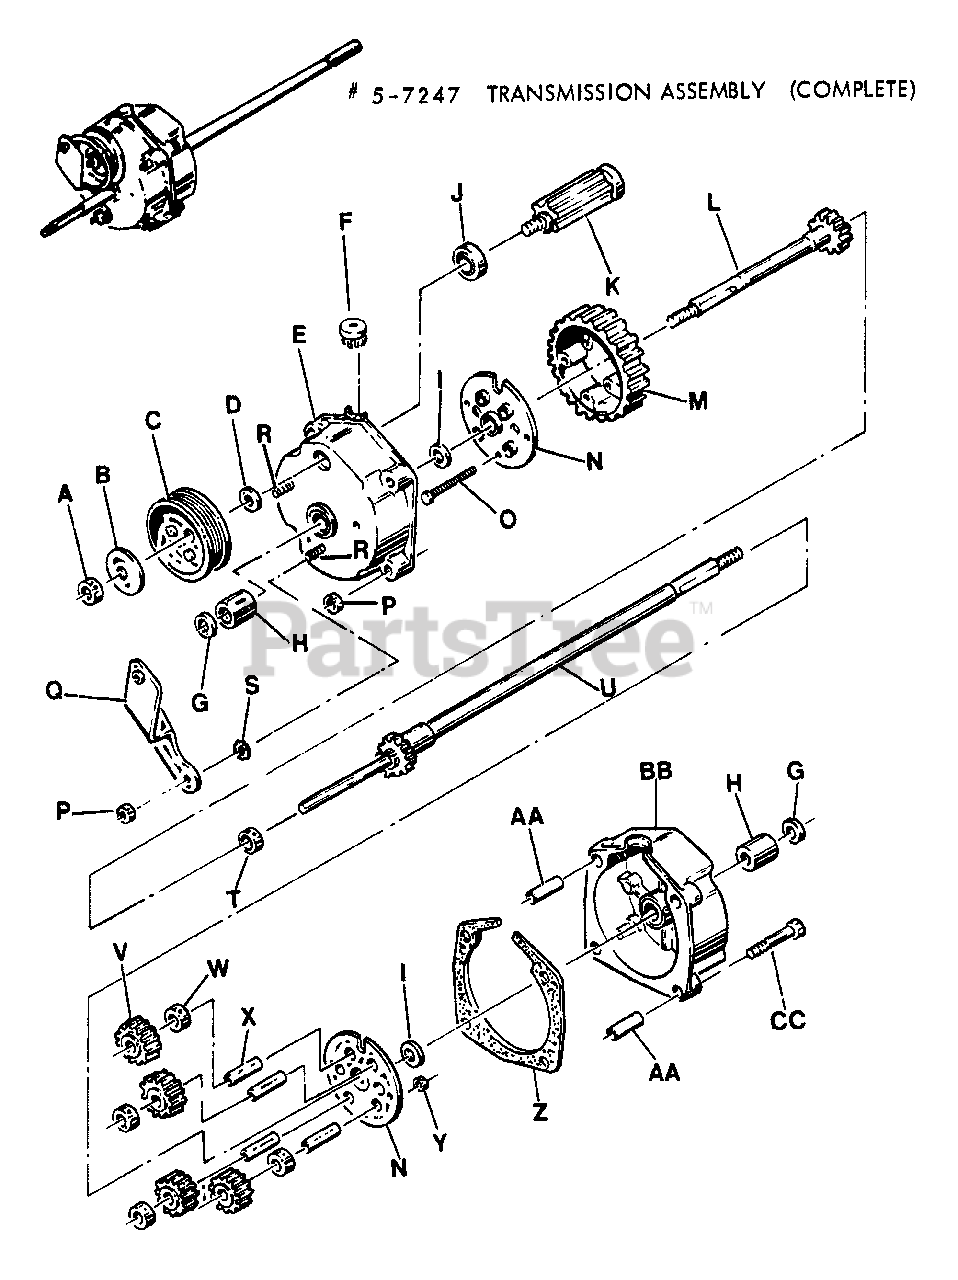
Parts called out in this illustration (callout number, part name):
57247	TRANSMISSION ASSEMBLY (COMPLETE)
A	NUT, 5/16-24 Hex Lock, Grade C
B	WASHER, Spring
C	PULLEY, Poly V-Belt
D	WASHER, Spring
E	HOUSING ASSEMBLY, Right
F	PLUG, Housing
G	SEAL
H	BEARING, Tapered O.D.
I	WASHER, Thrust
J	BEARING, Ball
K	ASSEMBLY, Gear Input
L	ASSEMBLY, Short Axle
M	GEAR, 46 Tooth Differential
N	PLATE
O	SCREW, #10-32 x 1-1/2" Hex Head Cap, Grade 5
P	NUT, 1/4-28 Hex Top Lock
Q	BRACKET, Differential
R	BOLT, 1 /4-28 x 1" Ribbed
S	WASHER, 1/4" Internal/External Tooth Lock
T	SPACER, Axle Gear
U	ASSEMBLY, Long Axle
V	GEAR, 12 Tooth Pinion
W	SPACER, Pinion Gear
X	SHAFT, Pinion
Y	NUT, #10-32 Hex Nyloc
Z	GASKET, Housing
AA	PIN, 3/8 x 7/16" Roll
BB	HOUSING ASSEMBLY, Left
CC	SCREW, 1/4-28 x 1-3/8" Hex Head Cap, Grade 5
